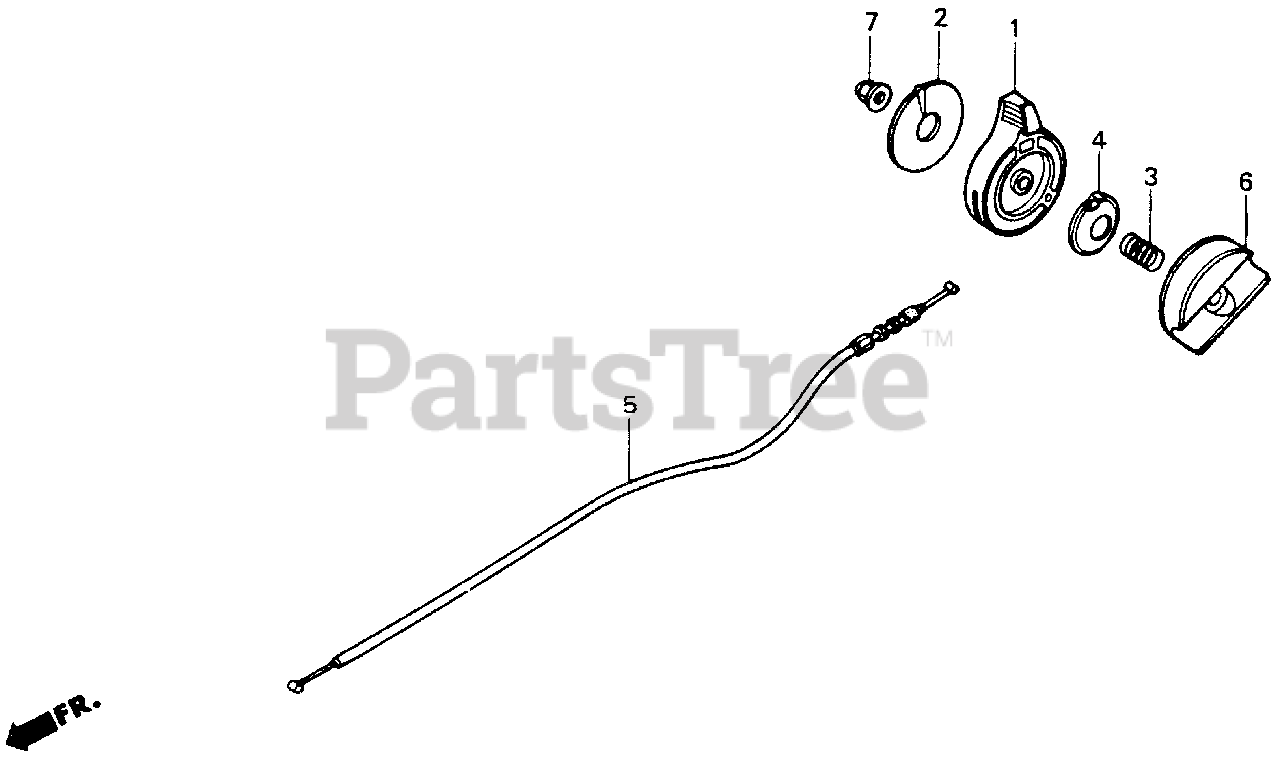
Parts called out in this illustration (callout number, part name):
1	LEVER, THROTTLE
2	PLATE, THROTTLE LEVER
3	SPRING, THROTTLE LEVER
4	SEAT, SPRING
5	CABLE, THROTTLE (NOT AVAILABLE)
6	COVER, CONTROL
7	NUT, FLANGE (6MM)
